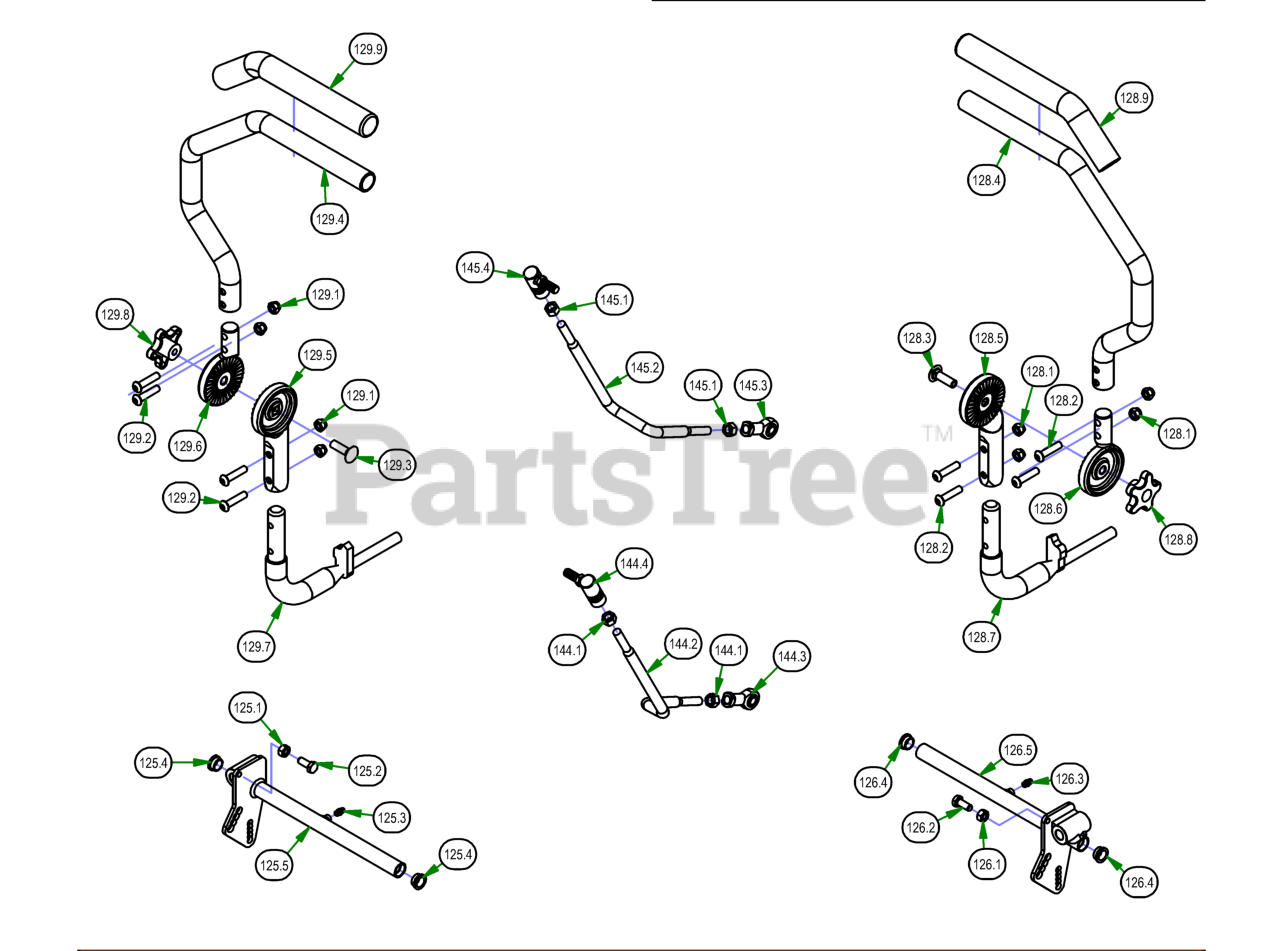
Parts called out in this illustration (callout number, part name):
125	2021 Maverick Drive Arm Actuator RH Assembly
125.1	5/16-18 HEX NUT ZINC
125.2	5/16-18 X 3/4 HEX CAP SCREW (GR.5) ZINC
125.3	1/4" Press in Grease Fitting
125.4	2019 Drive Arm Bushing
125.5	2021 Drive Actuator RH Weldment
126	2021 Maverick Drive Arm Actuator LH Assembly
126.1	5/16-18 HEX NUT ZINC
126.2	5/16-18 X 3/4 HEX CAP SCREW (GR.5) ZINC
126.3	1/4" Press in Grease Fitting
126.4	2019 Drive Arm Bushing
126.5	2021 Drive Actuator LH Weldment
128	2018 Adjustable Steering Arm - Left
128.1	5/16-18 NYL INS L/N ZC
128.2	5/16-18 UNC X 1-3/8" BHCS, TORX DRIVE, GR 5
128.3	3/8-16 X 1-1/4 CARRIAGE BOLT ZINC
128.4	Upper Tube-Adjustable Steering
128.5	2018 Lower Adjuster - Steering Arm- Left
128.6	2018 Upper Adjuster - Steering Arm- Left
128.7	Steering Arm Elbow (Left)
128.8	Black Knob for Adjustable Steering Arm
128.9	Rubber Grip
129	2018 Adjustable Steering Arm - Right
129.1	5/16-18 NYL INS L/N ZC
129.2	5/16-18 UNC X 1-3/8" BHCS, TORX DRIVE, GR 5
129.3	3/8-16 X 1-1/4 CARRIAGE BOLT ZINC
129.4	Upper Tube-Adjustable Steering
129.5	2018 Lower Adjuster - Steering Arm- Right
129.6	2018 Upper Adjuster - Steering Arm- Right
129.7	Steering Arm Elbow (Right)
129.8	Black Knob for Adjustable Steering Arm
129.9	Rubber Grip
144	Push Rod-Right
144.1	3/8" Fine Threaded Jam Nut
144.2	Push Rod - Right
144.3	Spherical Rod End - Outlaw
144.4	Quick Release Ball Joint
145	Push Rod-Left
145.1	3/8" Fine Threaded Jam Nut
145.2	Push Rod - Left
145.3	Spherical Rod End - Outlaw
145.4	Quick Release Ball Joint
